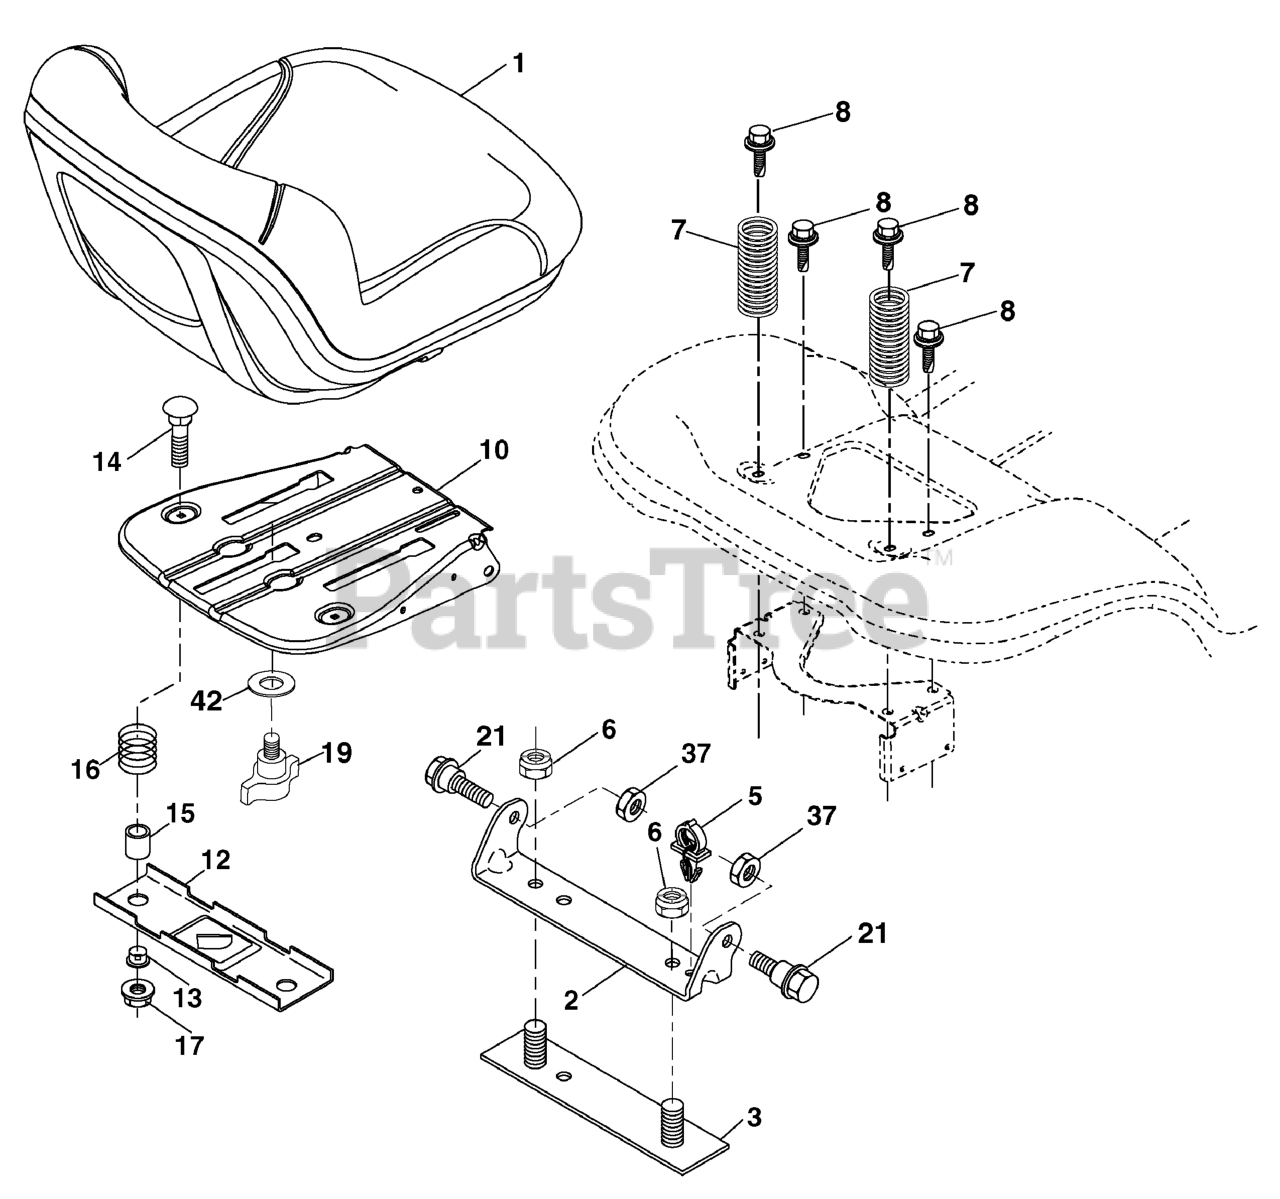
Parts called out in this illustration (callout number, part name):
2	Bracket Pivot Fender
3	Strap, Asm Fender
5	Clip Push-In
6	Nut, Lock w/Ins. 3/8-16 unc
7	Spring, Seat Cprsn
8	Bolt 5/16-18 unc x 3/4 w/Sems
10	Pan, Seat
12	Bracket Mounting Seat
13	Bushing Snap
14	Bolt 1/4-20 x 1-1/2
15	Spacer Split
16	Spring
17	Nut Lock 1/4
19	Knob Seat
21	Bolt, Shoulder 5/16-18
37	Nut, Lock 5/16-18 unc
42	Washer Cup Seat
